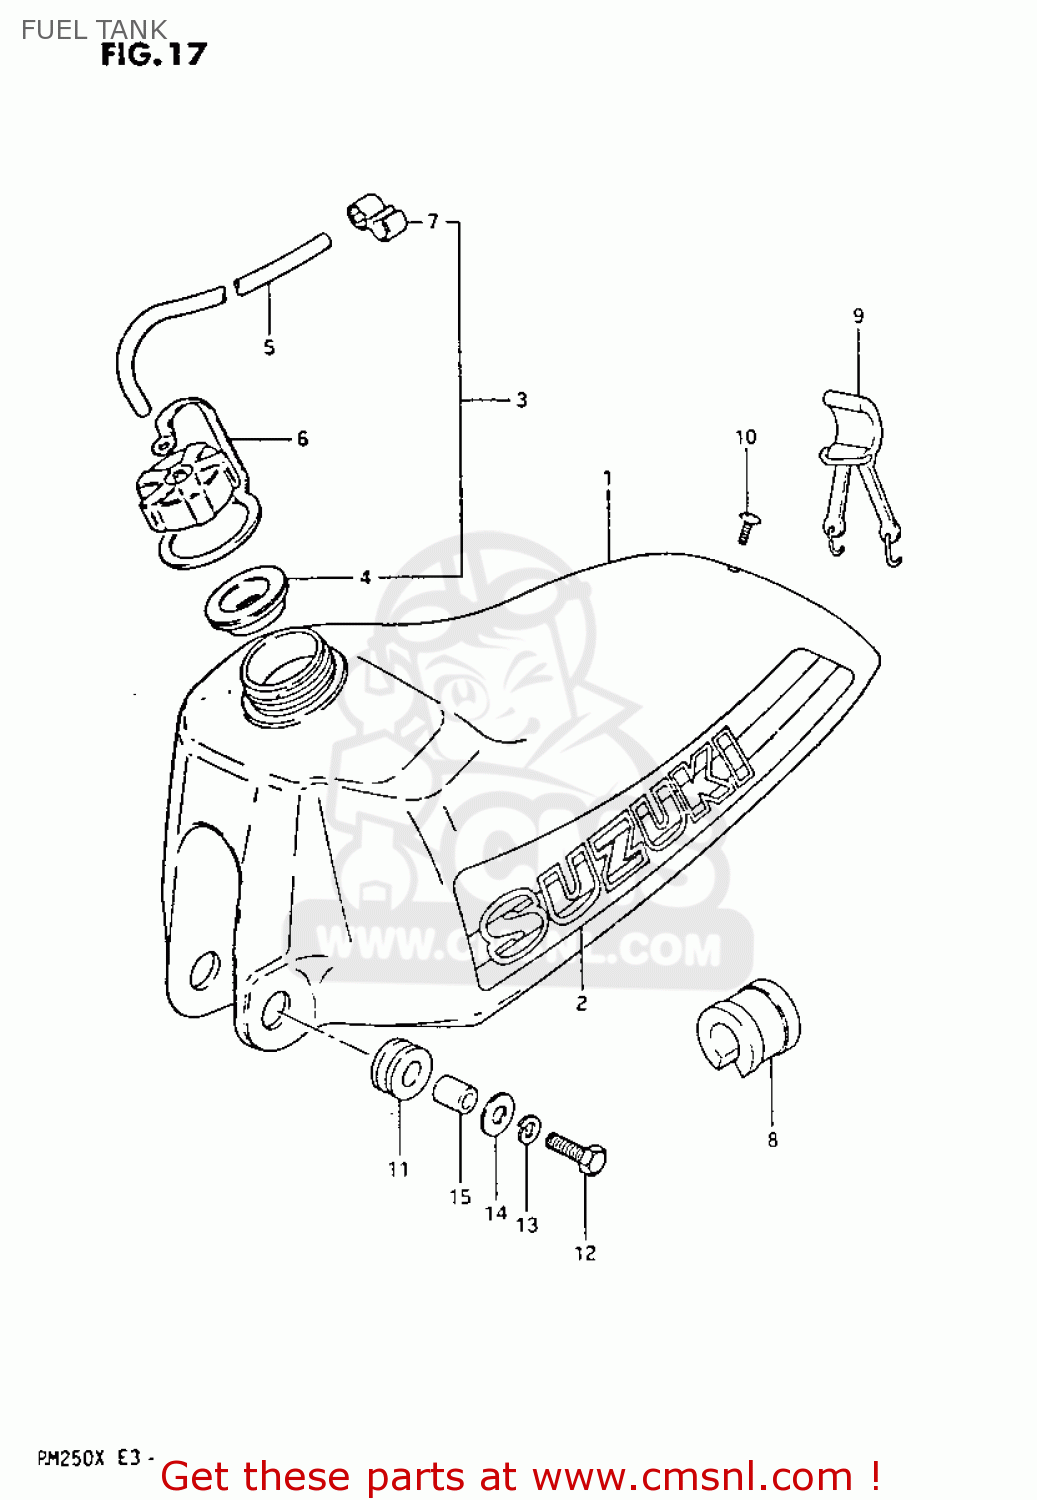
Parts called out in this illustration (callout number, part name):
1	TANK ASSEMBLY,FUEL
2	TAPE SET,FUEL TANK
3	CAP,FUEL TANK FILLER
4	GASKET,FUEL TANK CAP (NAS)
5	HOSE
6	BAND,FUEL TANK CAP
7	CLAMP,BREATHER HOSE
8	CUSHION,FUEL TANK UPR
9	BAND,FUEL TANK,REAR
10	SCREW (6X15)
11	CUSHION
12	BOLT
13	LOCK WASHER
14	WASHER (8.5X29X1.6)
15	SPACER (8.8X12X15.5)
